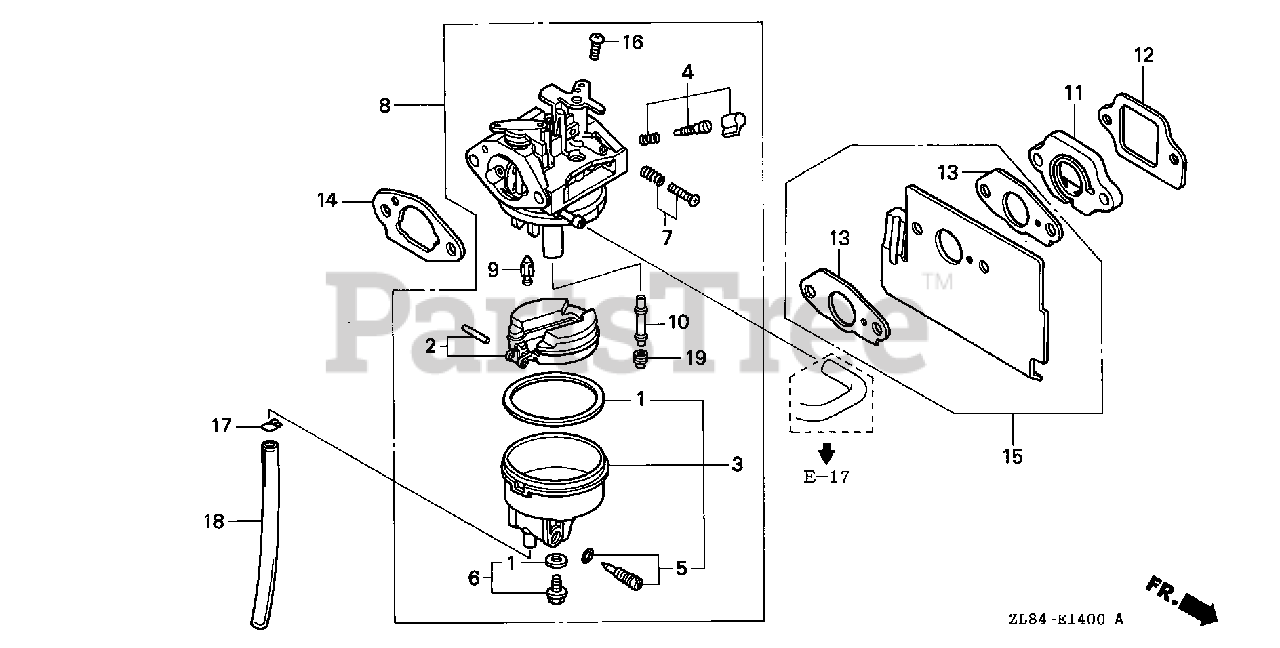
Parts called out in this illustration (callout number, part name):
1	GASKET SET
2	FLOAT SET
3	CHAMBER SET, FLOAT
5	SCREW SET, DRAIN
6	SCREW SET B
7	SCREW SET
8	CARBURETOR ASSY. (BB63B B)
9	VALVE, FLOAT
10	NOZZLE, MAIN
11	INSULATOR, CARBURETOR
12	GASKET, INSULATOR
13	GASKET, CARBURETOR
14	GASKET, CARBURETOR (CHOKE SIDE)
15	GUIDE, AIR
16	SCREW, PAN (5X6)
17	CLIP, TUBE (B6.5)
18	BULK HOSE, VINYL (4X7X8000) (4X7X150)
19	JET, MAIN (#55)
19	JET, MAIN (#58)
19	JET, MAIN (#60)
22	SCREW SET
